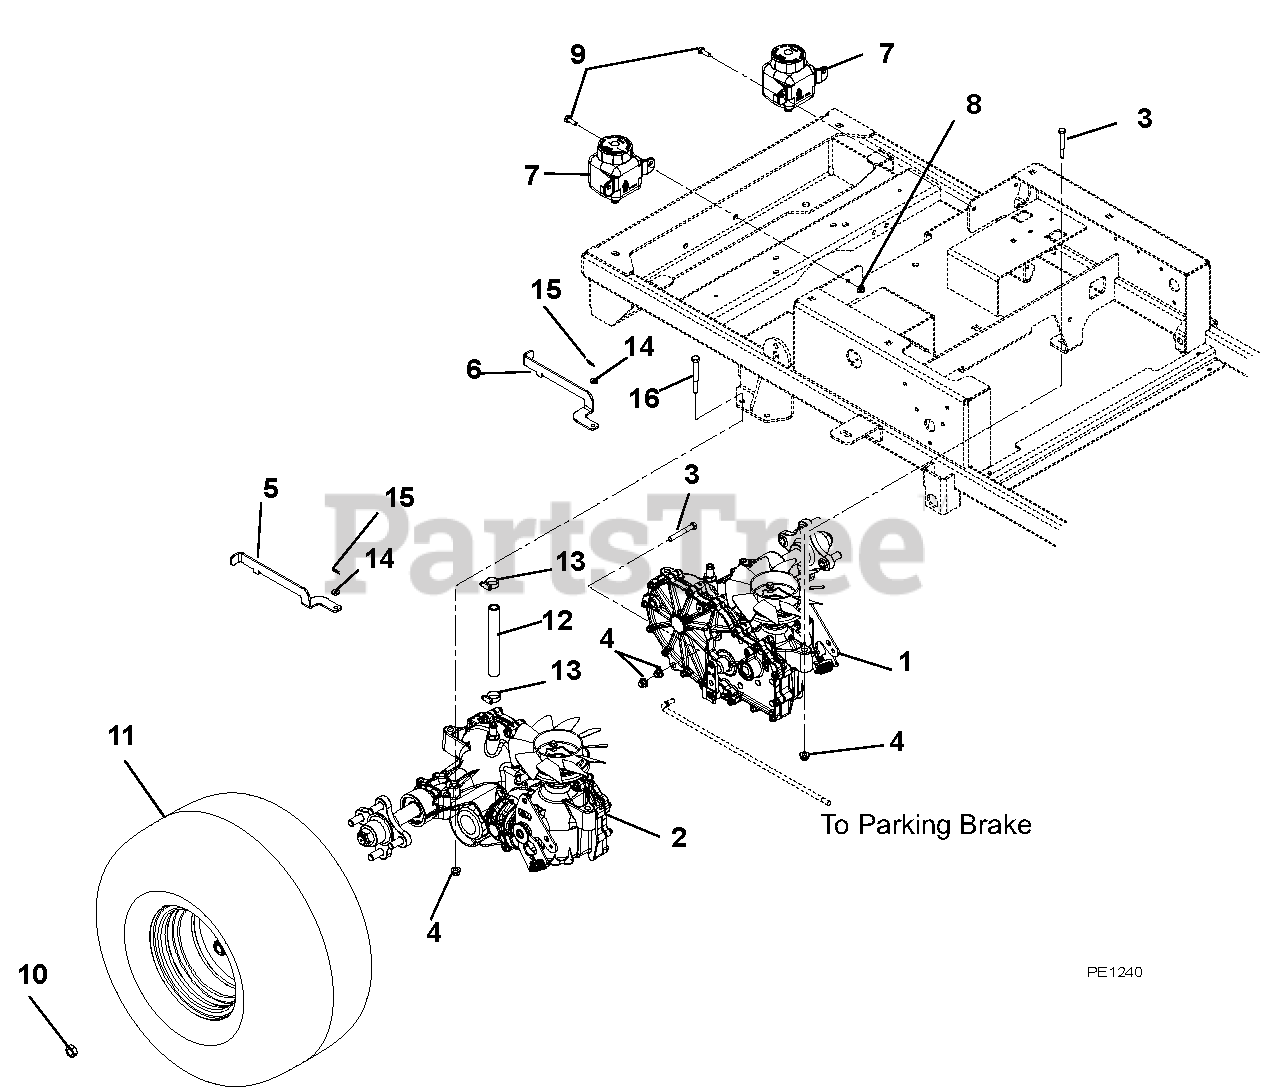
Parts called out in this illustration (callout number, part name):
1	Transaxle, ZT2800 Left Hand
2	Transaxle, ZT2800 Right Hand
3	Bolt, Hex .31-18 x 2.25 Grade 5
4	Nut 5/16-18 Flange Nyloc
5	Dump Valve, Right Hand
6	Dump Valve, Left Hand
7	Tank, Expansion ZT2800
8	Nut, Locking Top Flange .25-20
9	Bolt, Hex .25-20 x .75 Grade 5
10	Nut, Wheel .50-20 13/16
11	Tire/Wheel Assembly, 20 x 10.0-8 Center
12	Hose, Oil Reservior
13	Clamp, .88 Diameter Hose
14	Washer, Flat Steel .265 x .50 x .087
15	Pin, Hair Internal .06 x .18 x .77
16	Bolt, Hex .31-18 x 2.75
